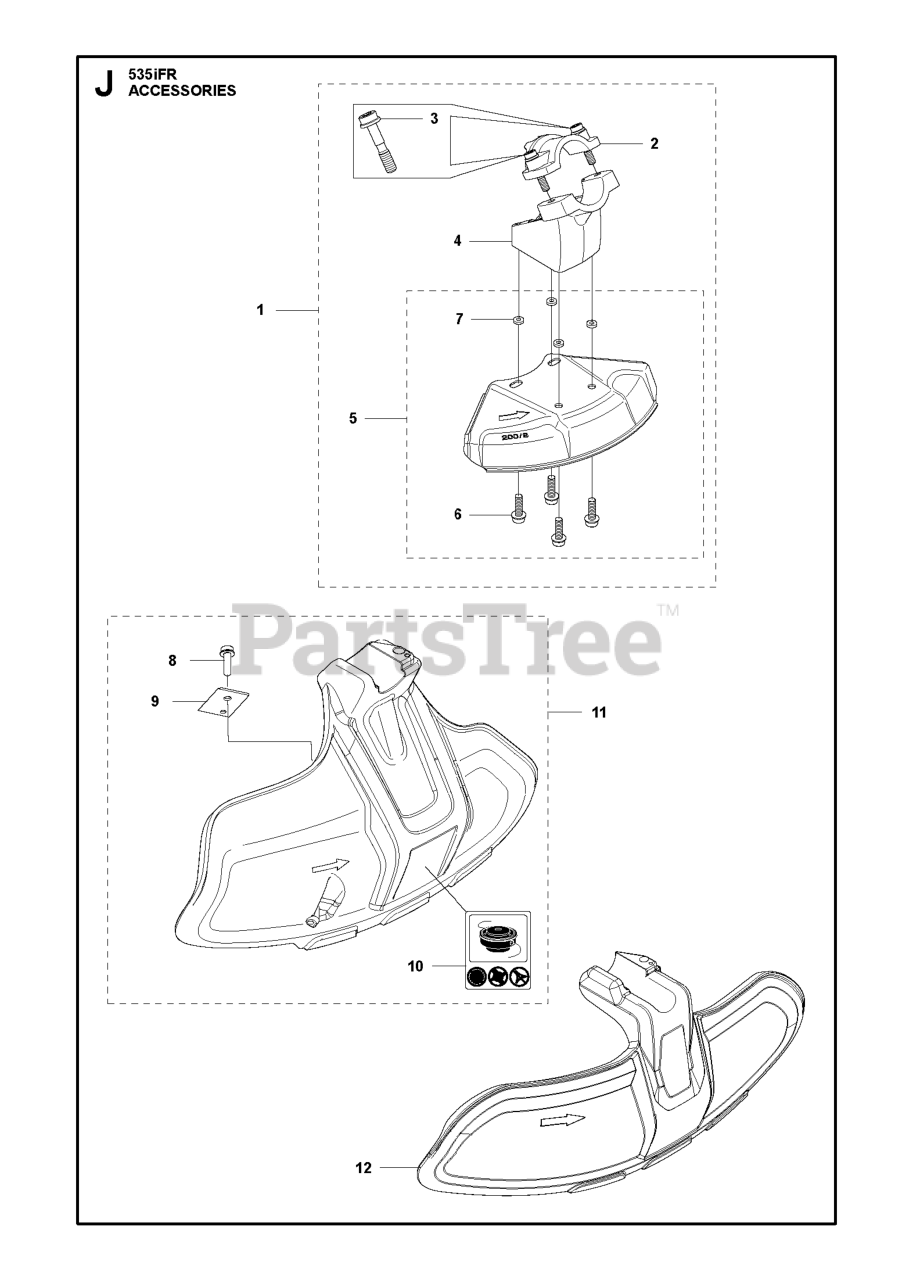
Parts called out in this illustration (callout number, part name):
1	SAW BLADE GUARD
6	SCREW ITXSCFM
7	LOCKING NUT
8	SCREW ITXSCFT PW4.8X16 T27 CH
